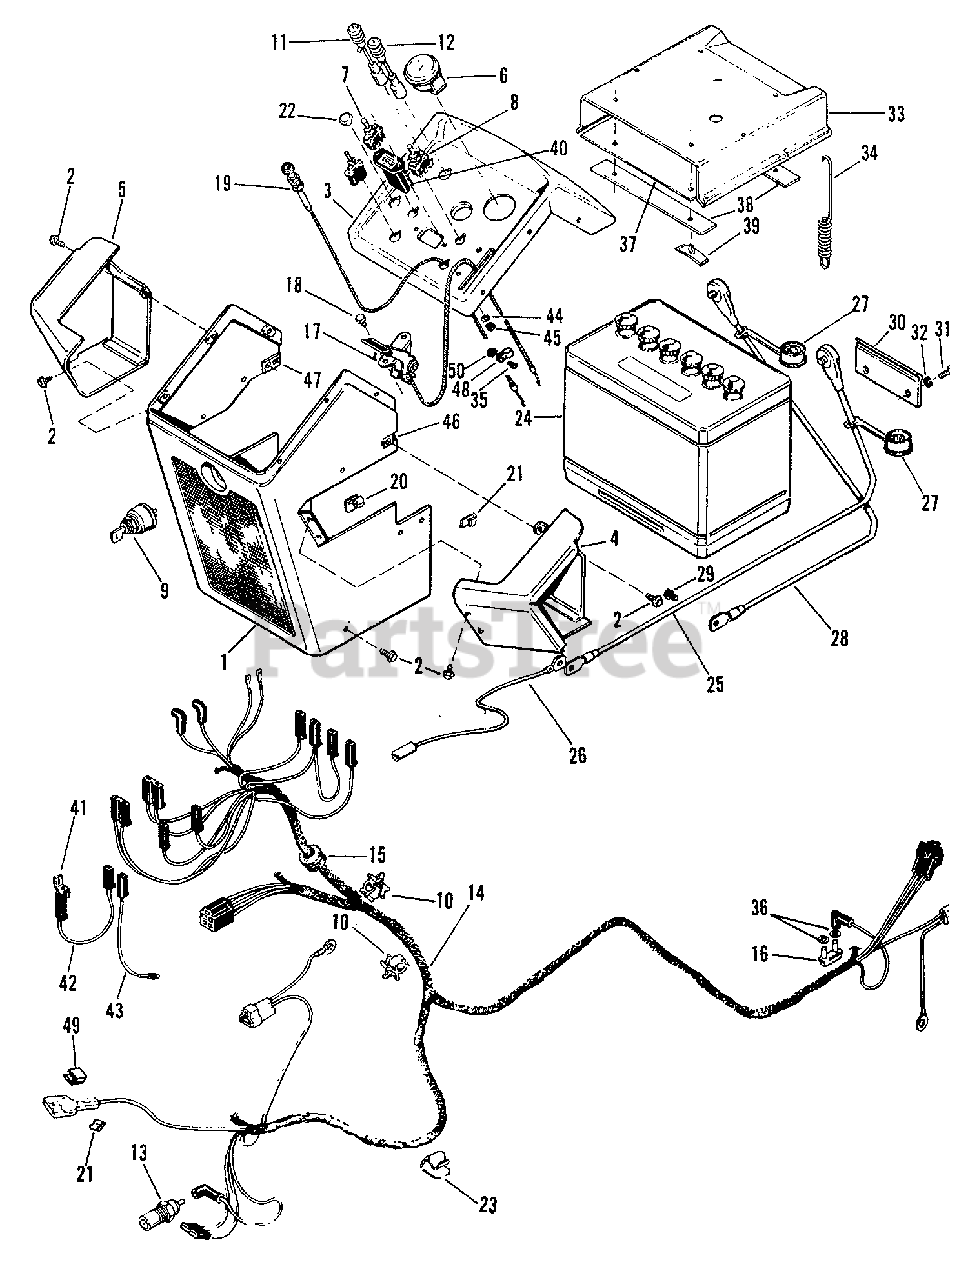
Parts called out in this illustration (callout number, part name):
1	BODY SUPPORT ASSEMBLY
2	SCREW, Thread Forming, 1/4"-20 x 3/8" Lg.
3	PANEL ASSEMBLY
4	PANEL ASSEMBLY, R.H.
5	PANEL ASSEMBLY, L.H.
9	SWITCH, Ignition
11	LIGHT, Indicator, Hot
12	LIGHT, Indicator, Oil
13	LIGHT, Indicator, Switch
14	HARNESS, Wiring
16	BREAKER, Circuit
17	THROTTLE, Control
18	SCREW, Thread Forming, 1/4"-20 x 5/8" Lg.
19	CONTROL, Choke
21	CLIP, Speed
22	BUTTON, Plug
25	CABLE, Positive
28	CABLE, Negative
29	SCREW, Taptite, 5/16-18 x 3/8" Lg.
31	CAPSCREW, Hex, 5/16-18 x 3/4" Lg.
32	LOCKWASHER, 5/16"
35	SCREW, Thread Form
36	WASHER, Paper
39	CLIP, Speed
40	METER, Hour
41	ADAPTOR, Two-Way
42	WIRE (to Ignition Switch)
43	WIRE (to Ground)
44	LOCKWASHER, External 1/4"
45	NUT, Hex, 1/4-20
46	NUT, Speed
47	NUT, Speed
50	WASHER, Shake-Proof
